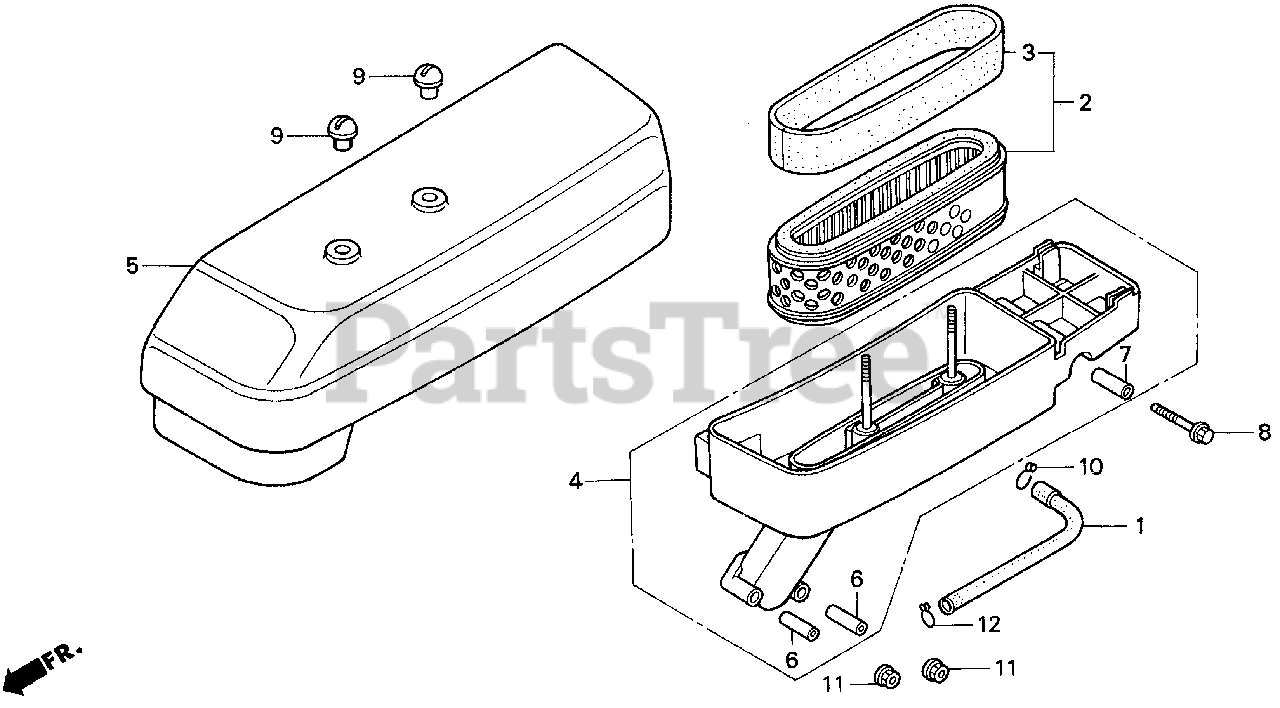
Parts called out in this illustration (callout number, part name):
1	TUBE, BREATHER
2	ELEMENT, AIR CLEANER
3	FILTER (OUTER)
4	HOUSING, AIR CLEANER
5	COVER, AIR CLEANER *R8* (BRIGHT RED)
6	COLLAR, AIR CLEANER
7	COLLAR B, AIR CLEANER
8	BOLT, FLANGE (6X35) (CT200)
9	NUT, AIR CLEANER COVER (6MM)
10	CLIP, TUBE
11	NUT, FLANGE (6MM)
12	CLIP, TUBE (B12)
